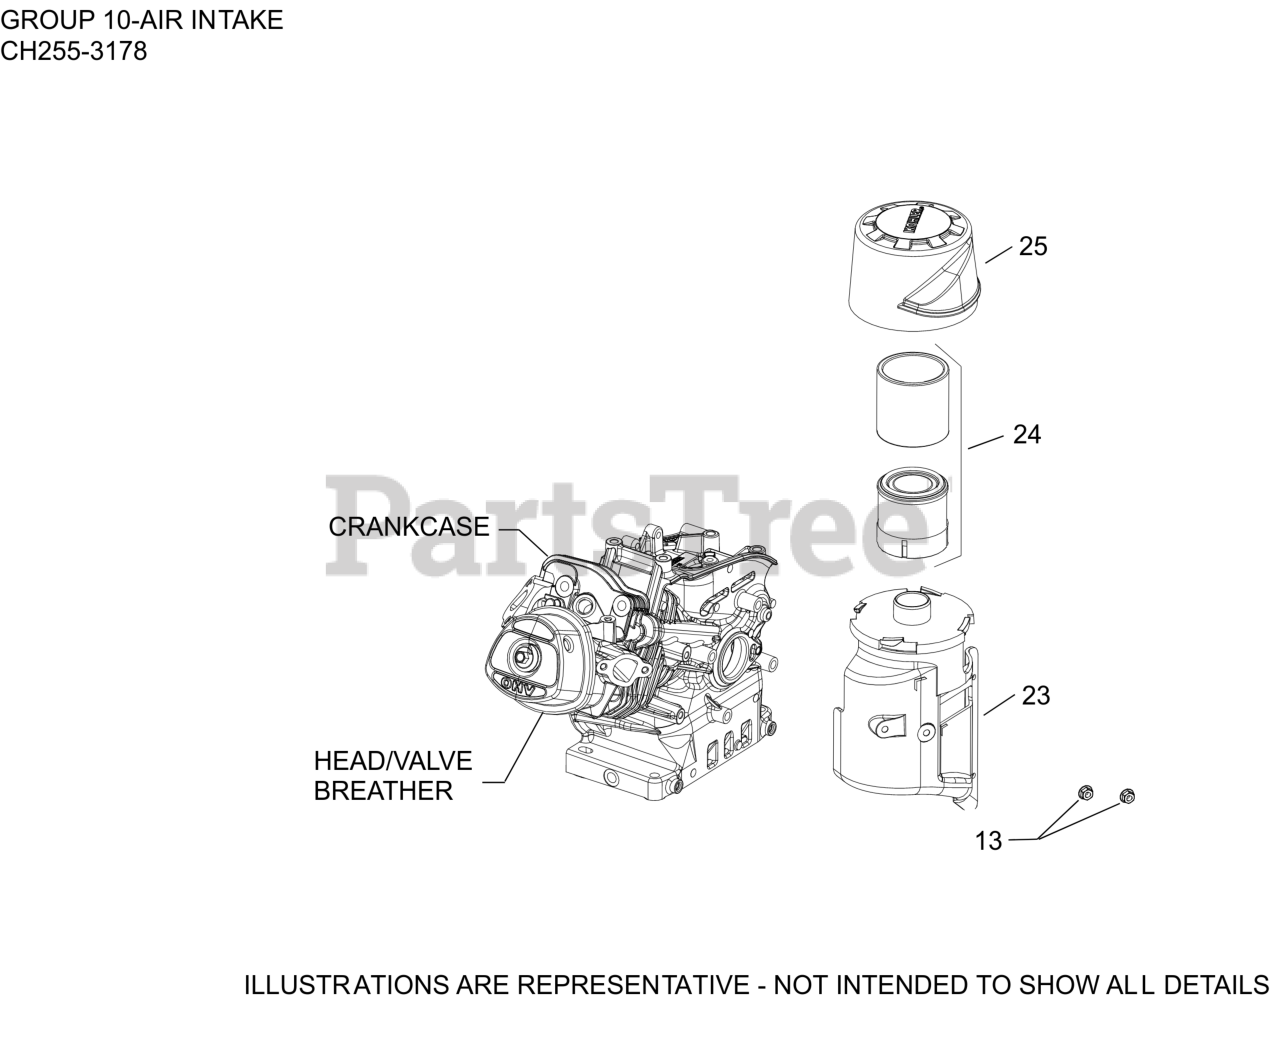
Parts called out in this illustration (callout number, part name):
13	NUT, HEX FLANGE LOCK (M6)
23	BASE, AIR CLEANER ASSEMBLY
24	ELEMENT, FILTER ASSEMBLY
25	COVER, AIR CLEANER ASSEMBLY
